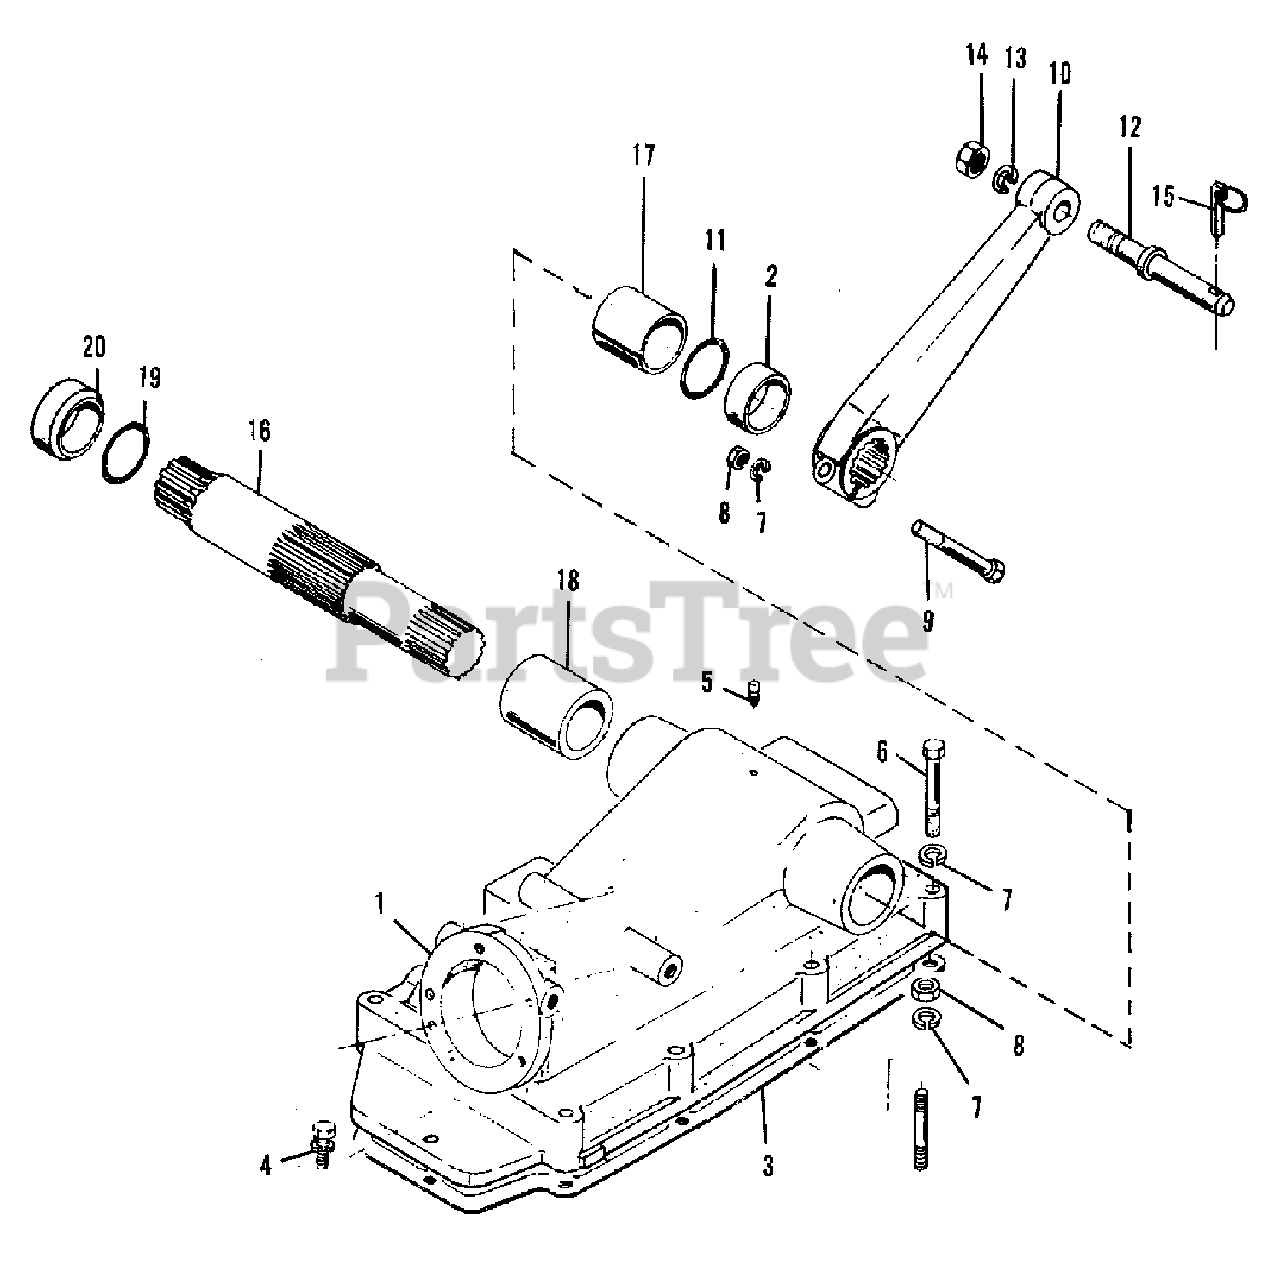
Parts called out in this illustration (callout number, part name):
1	HOUSING, lift
2	COLLAR (B)
3	GASKET, housing
6	CAPSCREW M10 x 55
7	LOCKWASHER, M10
13	LOCKWASHER, M16
15	PIN, quick
16	SHAFT, lift arm
20	COLLAR (A)
